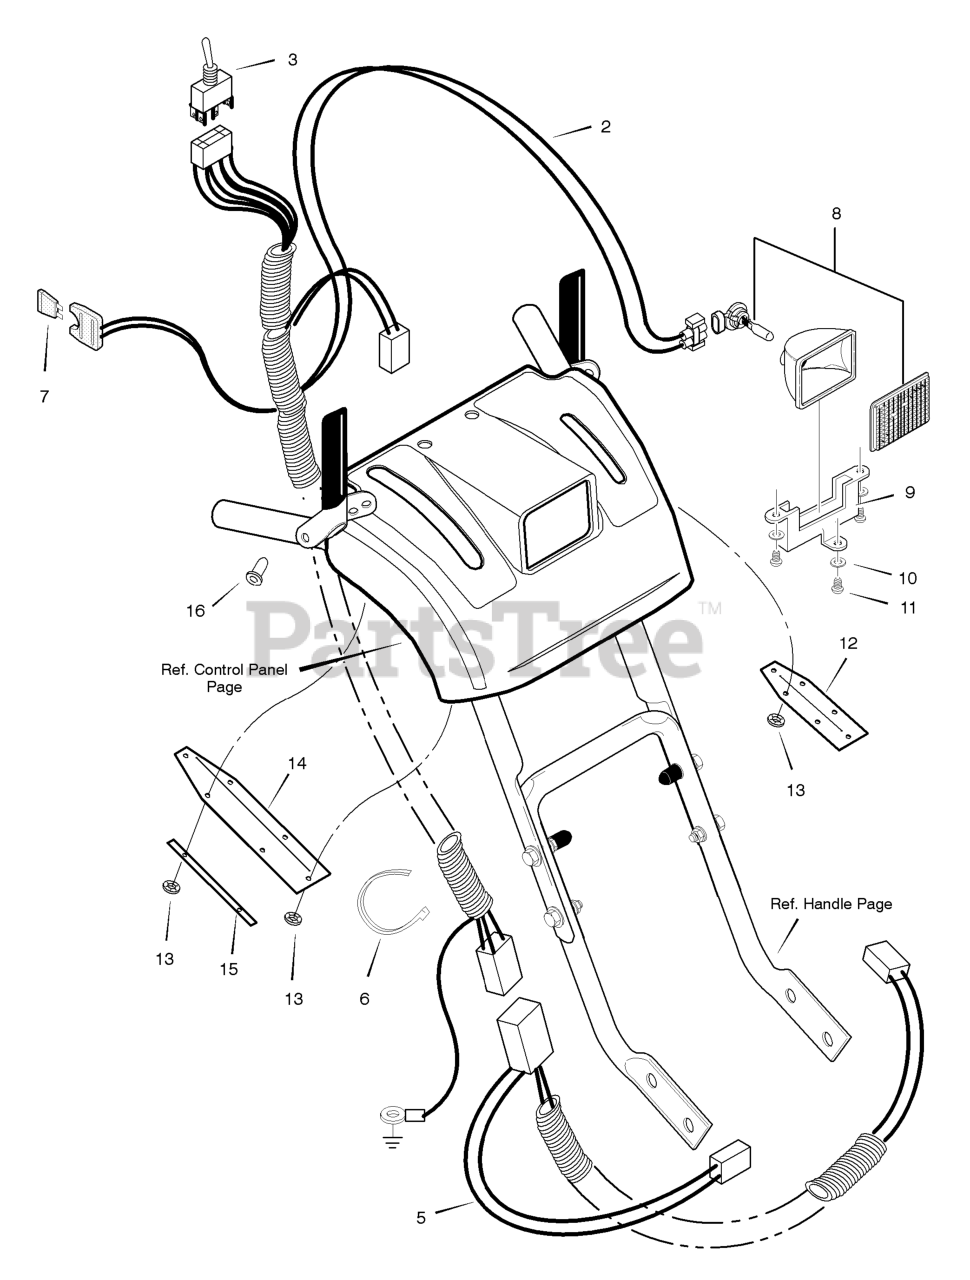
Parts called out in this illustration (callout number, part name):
2	WIRE HARNESS, UPPER
3	SWITCH, CHUTE ROTATION
5	WIRE HARNESS, LOWER
6	TIE, CABLE
7	FUSE, 7.5 AMP AUTOMOTIVE
8	HEADLIGHT ASSEMBLY *
9	BRACKET
10	WASHER, FLAT
11	SCREW #8 X .50
13	NUT, PUSH
16	RIVET, 0.125 x 0.23
